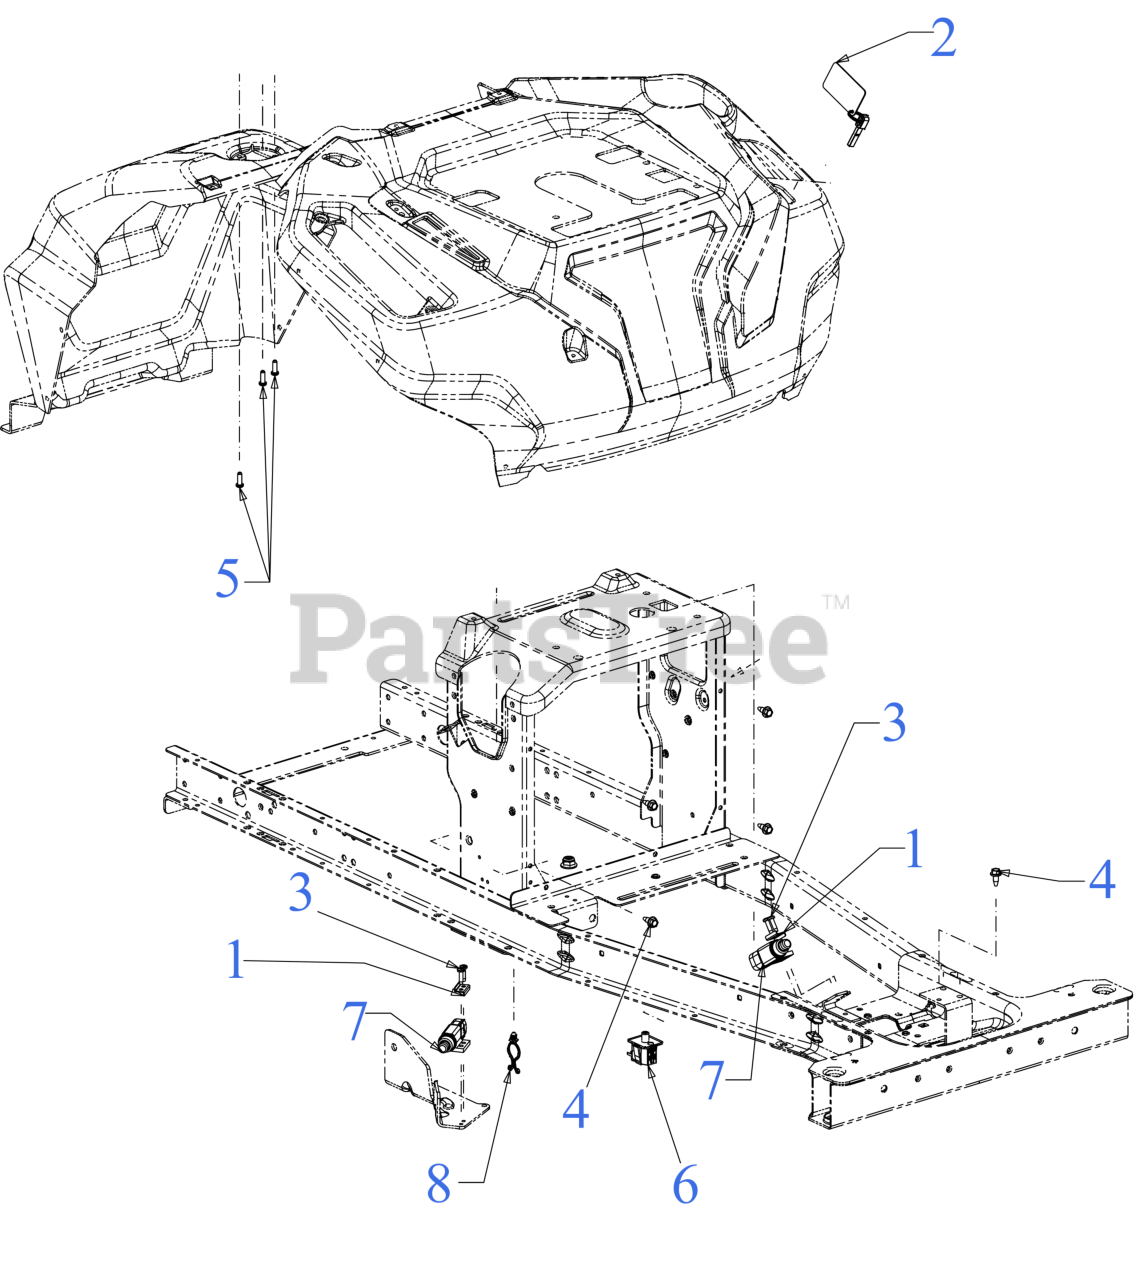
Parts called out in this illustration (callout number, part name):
1	PLATE-SWITCH
2	MAGNETIC KEY
3	SCREW #
4	SCREW 1/4-20X.625
5	SCREW #12-16 x .625
6	SEAT SWITCH (NC/NO)
7	SEALED PLUNGER SWITCH
8	TWIST LOCK CLIP
